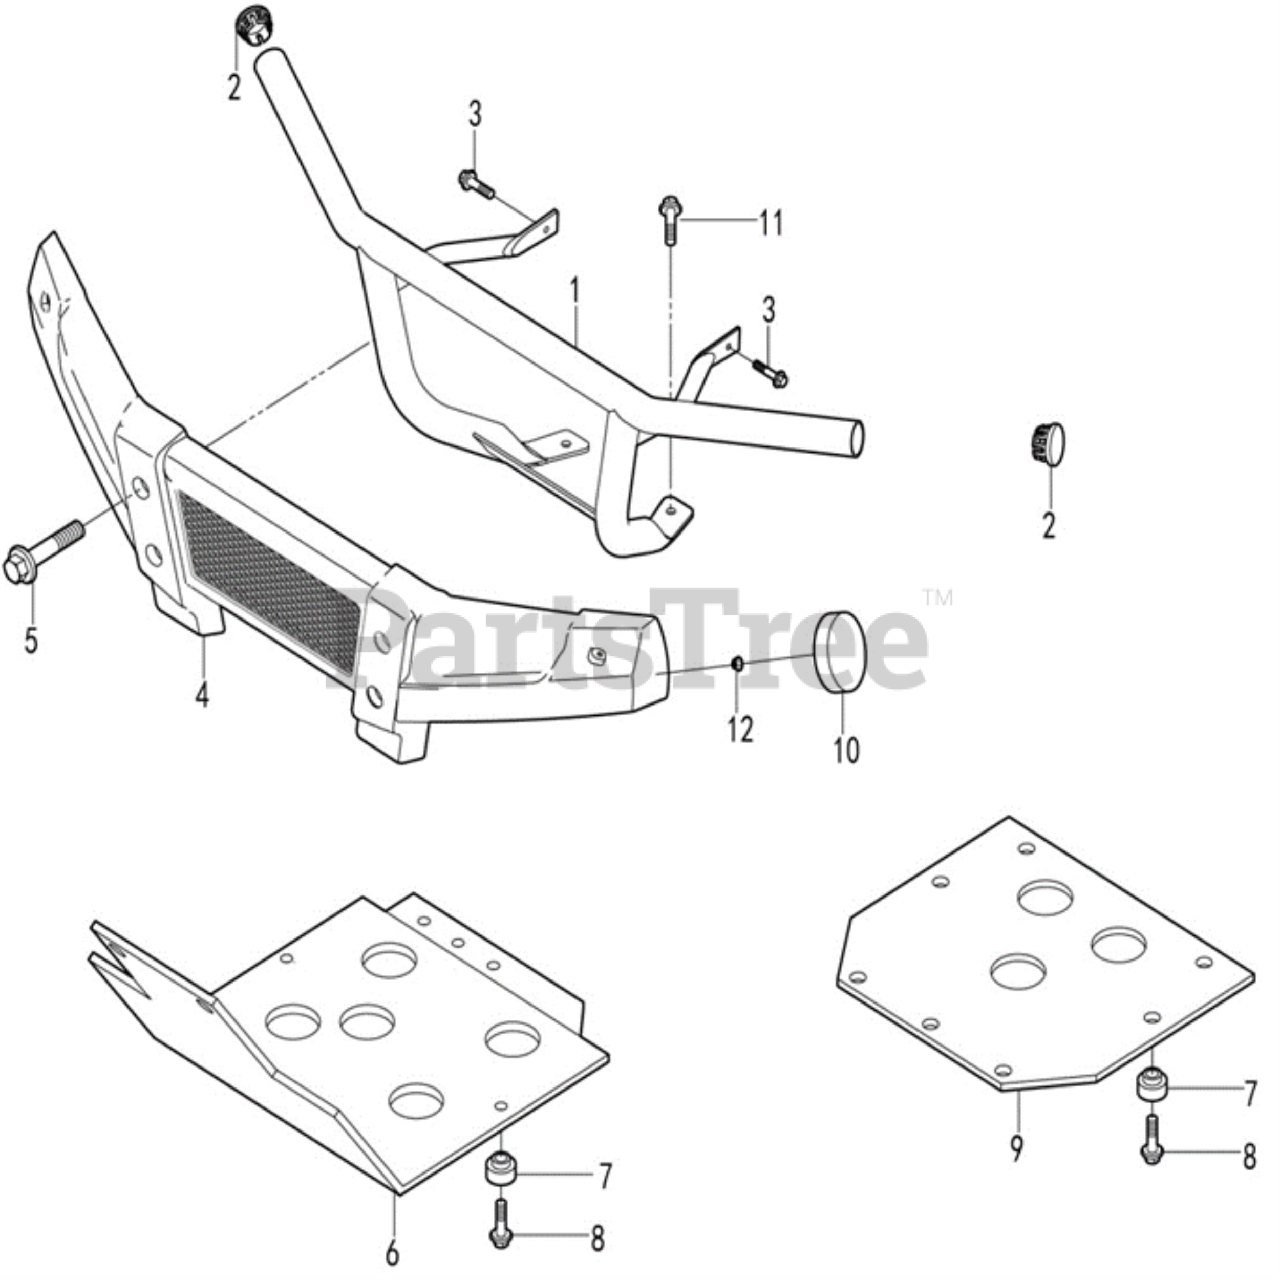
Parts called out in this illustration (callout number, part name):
1	welding assembly,front bumper
2	Round Plastic Plug 44
3	Hexagon Flange bolt M10X1.25X20
4	Protective plate,front bumper
5	Cross Large Plate Head Screw M6X16
6	Lower Backplate, Front Bumper
7	Cap-shaped cushion
8	Hexagon Flange Bolt M6X16
9	Rear Bottom Protective Plate I
10	Side Reflector
11	Flange Bolt M12X1.25X20
12	Flange nut M5
